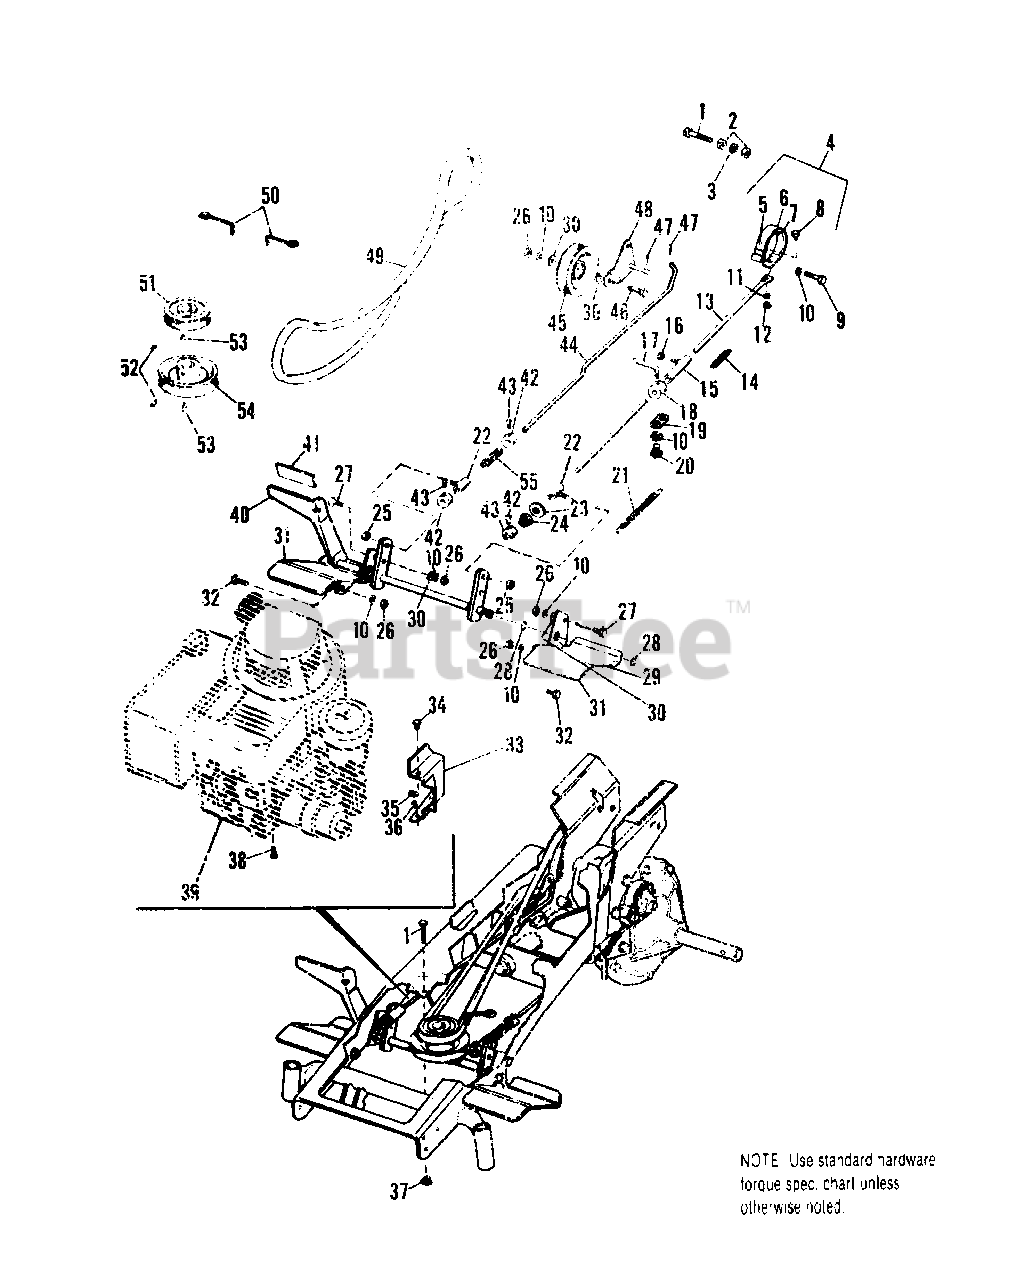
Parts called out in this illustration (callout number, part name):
1	CAPSCREW, Hex Hd., 5/16-18 x 1-1/2
2	NUT, Hex, Full, 5/16-18
3	LOCKWASHER, 5/16
4	BAND ASSY., Brake
5	RIVET, #7 x 1/4
6	BAND, Brake
7	LINING, Brake
8	CAPSCREW, Hex, 1/4-20 x 1/2
9	CAPSCREW, Hex Hd., 3/8-16 x 1-1/2
10	LOCKWASHER, 3/8
11	LOCKWASHER, 1/4
12	NUT, Hex, Full, 1/4-20
13	ROD, Brake
14	SPRING (990776 & 990777 Only)
15	GUIDE ASSY., Rod (990776 & 990777 Only)
15	GUIDE ASSY., Rod
16	LOCKNUT, Hex, 1/4-20
17	LOCK, Parking Brake
18	COLLAR, Parking Brake
19	ANCHOR, Spring (990776 & 990777 Only)
20	SCREW, Hex, Taptite, 3/8-16 x 1/2
21	SPRING, Return
22	GUIDE ASSY., Rod
23	WASHER, Plain, 3/8
25	LOCKNUT, Hex, 5/16-18
26	NUT, Hex, Full, 3/8-16
27	CAPSCREW, Hex Hd., 3/8-16 x 1
28	RING, Retaining
29	FOOTREST, L.H.
30	WASHER, Plain, 5/16
31	COVER, Footrest
32	CAPSCREW, Hex Hd., 3/8-16 x 3/4
33	DEFLECTOR, Muffler
34	SCREW, Self Tapping, #14 x 5/8
35	NUT, Speed
36	SCREW, Hex, Taptite, 1/4-20 x 3/8
37	LOCKNUT, Hex, Flange, 5/16-18
38	SCREW, Hex, Washer Hd., 3/8-16 x 1-1/4
40	SHAFT ASSY., Clutch
41	PAD, Pedal
42	COLLAR, Set
43	SETSCREW, 1/4-20 x 3/8
44	ROD, Clutch
45	PULLEY, Idler
46	CAPSCREW, Hex Hd., 3/8-16 x 1-1/4
47	PIN, Cotter, 1/8 x 3/4
48	BRACKET ASSY., Pulley
49	V-BELT, Drive
50	STOP, Belt
51	PULLEY, Engine, Small
52	SETSCREW, 5/16-18 x 1/2
54	PULLEY, Engine, Large
